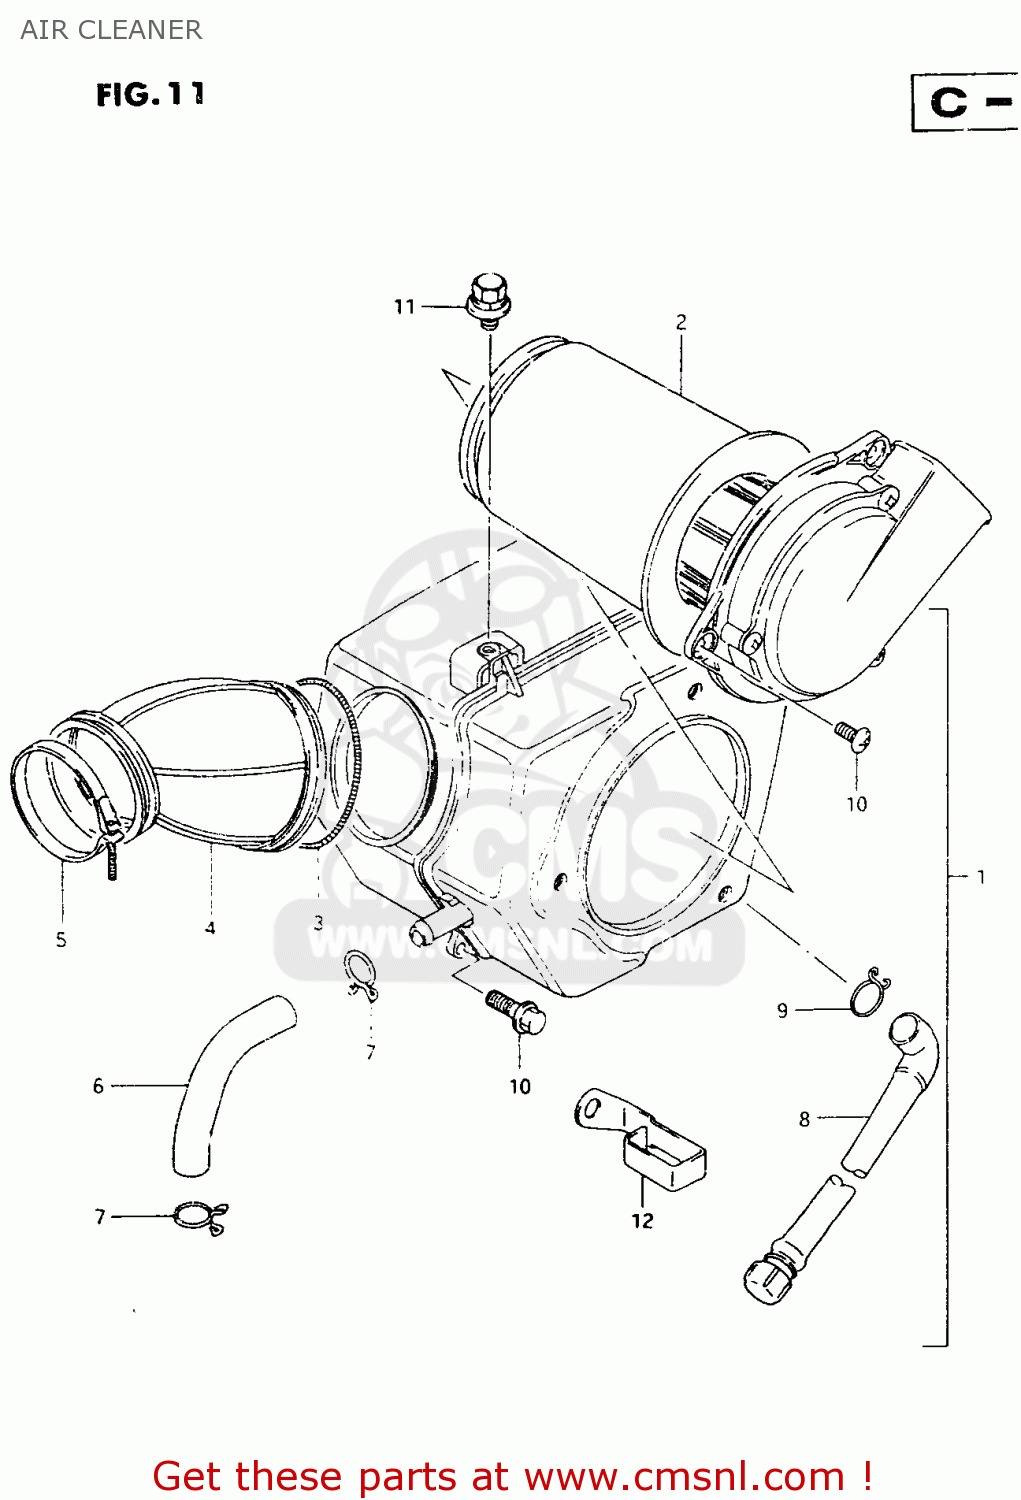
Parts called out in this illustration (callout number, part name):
1	CLEANER ASSY, AIR
2	FILTER
3	CLAMP,AIR CLEANER SIDE
4	TUBE,OUTLET
5	CLAMP
6	TUBE,BREATHER
7	CLIP
8	TUBE,DRAIN
9	CLIP
10	SCREW
11	BOLT
12	CLAMP,AIR CLEANER DRAIN TUBE
